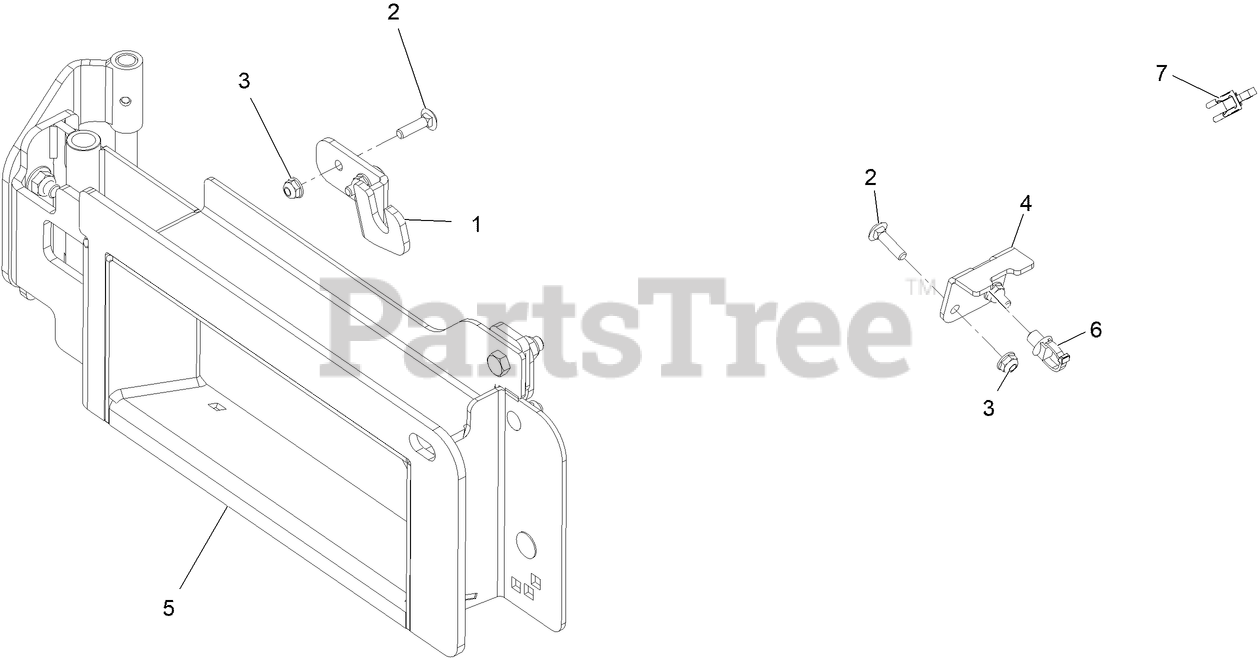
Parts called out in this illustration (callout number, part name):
1	BRKT-OCD CABLE
2	SCREW-CARR
4	BRKT-CABLE
5	KIT-ADAPTOR, ACCY. (SERIES 3)
6	CLIP-TIE
7	Clip-Edge
